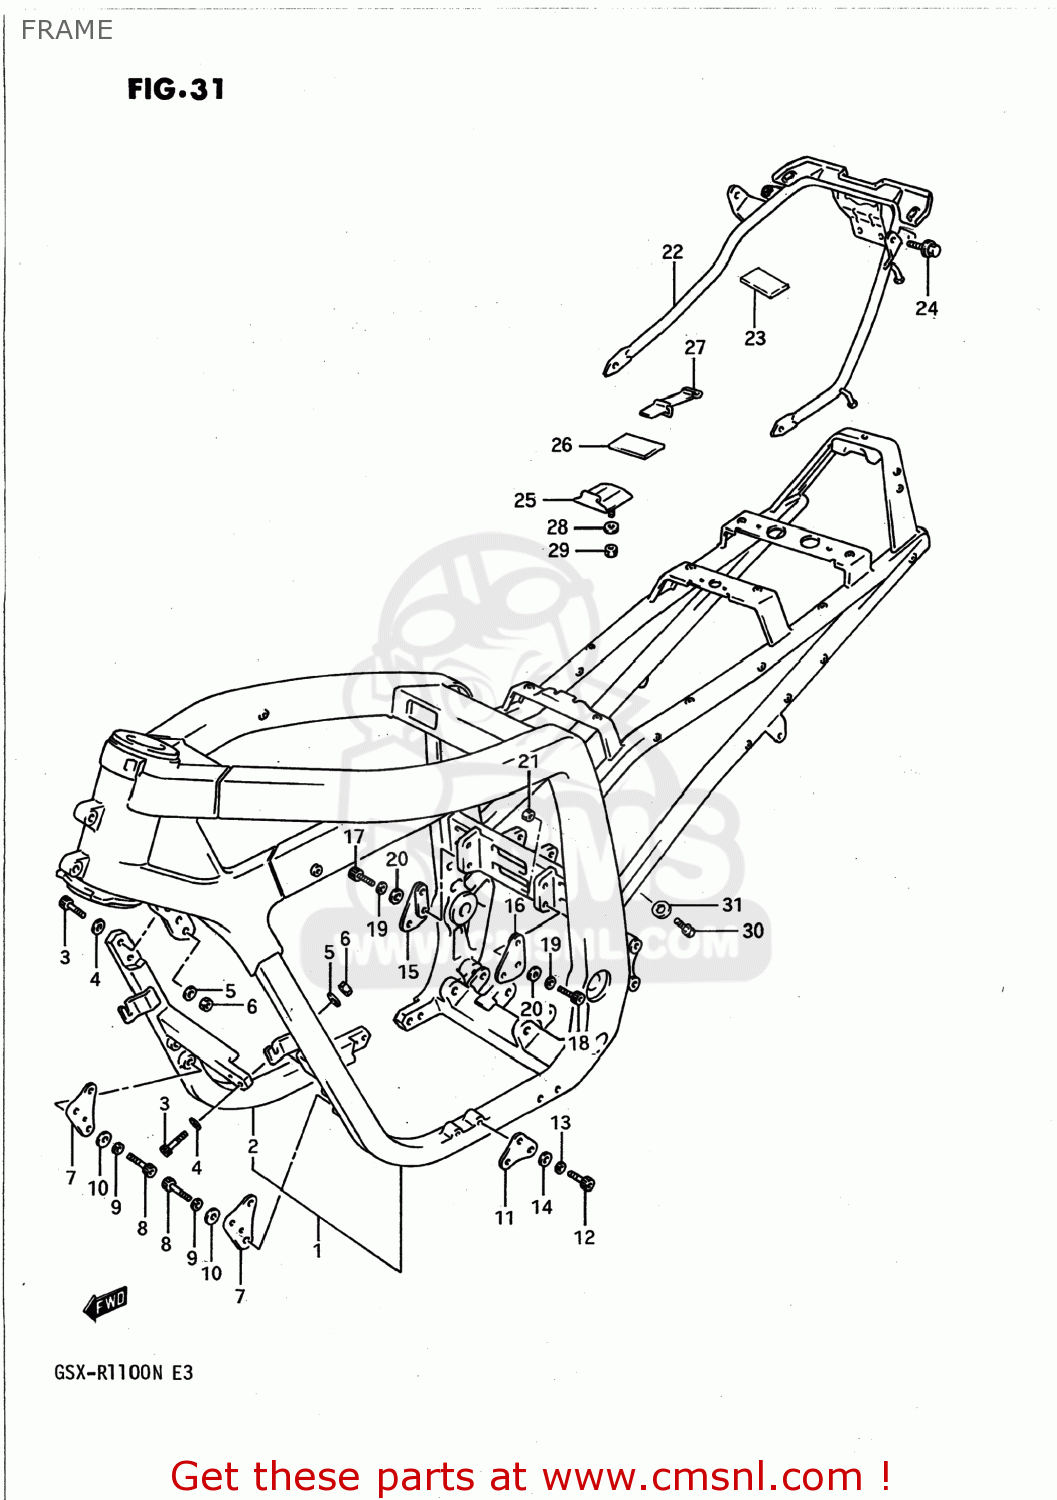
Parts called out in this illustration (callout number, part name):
1	FRAME
2	TUBE COMP,FRAME DOWN,RIGHT
3	BOLT, LH
4	WASHER (10.1X21X2.3)
5	WASHER
6	NUT
7	PLATE,ENG MTG NO.1
8	BOLT, FRONT LH
9	WASHER,LOCK
10	WASHER (8.2X20X1.6)
11	PLATE,ENGINE MOUNT NO.2
12	BOLT, FRONT LH
13	WASHER,LOCK
14	WASHER (8.2X20X1.6)
15	PLATE,ENGINE MOUNT NO.3,R
16	PLATE,ENGINE MOUNTING NO
17	BOLT(8X22)
18	BOLT, FRONT RH
19	WASHER,LOCK
20	WASHER (8.2X20X1.6)
21	NUT
22	GRIP COMP,REAR
23	TAPE,FRAME PROTECTOR
24	BOLT
25	HOLDER,TOOL
26	CUSHION
27	BAND
28	WASHER
29	NUT
30	BOLT
31	GASKET(6.2X11X1) (NAS)
